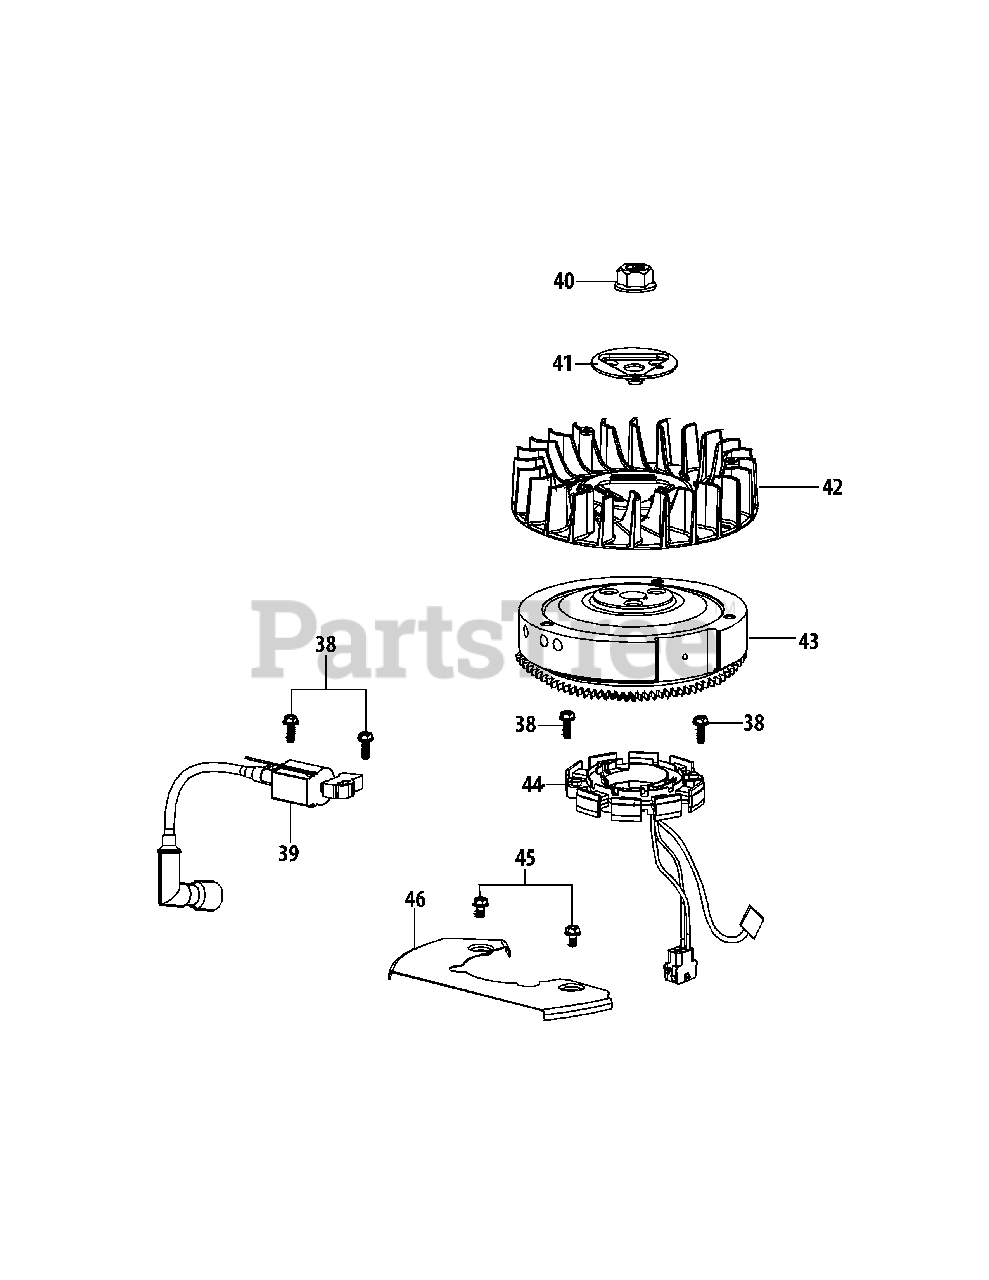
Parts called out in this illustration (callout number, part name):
38	Bolt M6×28
39	Ignition Coil Assembly
40	Flywheel Nut M16×1.5
42	Cooling Fan
44	Coil Assy.,Charge
45	Bolt M6×10
